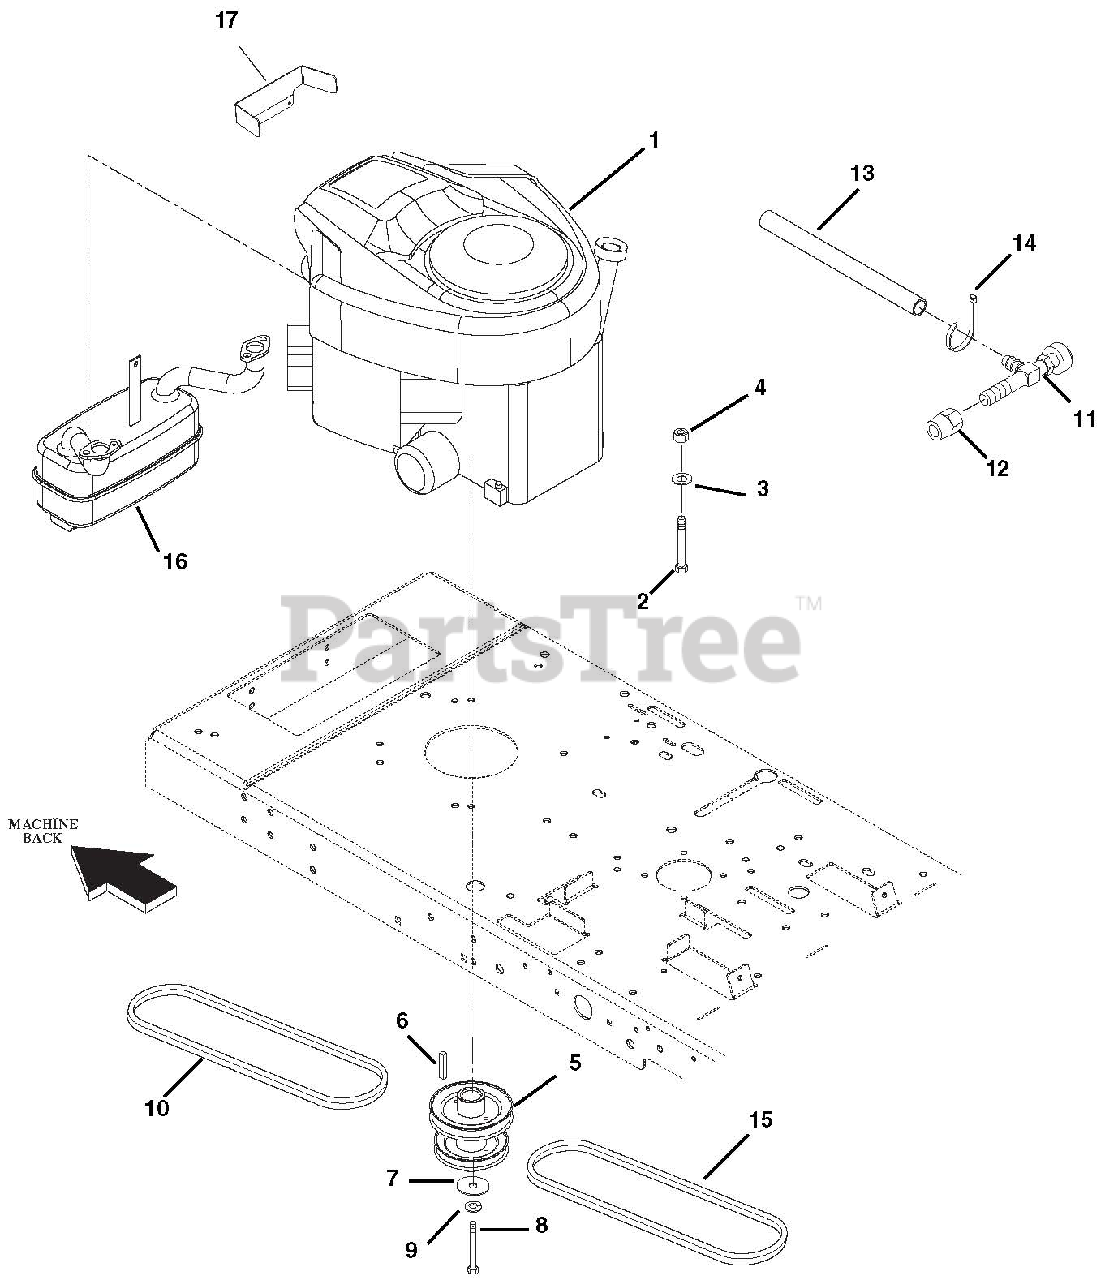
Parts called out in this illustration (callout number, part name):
1	ENGINE, B&S INTEK 20HP V TWIN
2	@BLT-HEX .31-18X1.50 GR5 YWZC
3	WSHR-FL-STL .328X1.0X.094 YWZC
4	@NUT-LK-NYL .312-18 YWZC
5	ENGINE SHEAVE 4.50
6	KEY-SQ .25 X 2.50 X .25 SAE
7	WSHR-FL-STL .469X2.00X.25 YWZC
8	BLT-HEX .44-20X3.00 GR5 YWZC
9	@WSHR-LK .44X.109 REG YWZC
10	V-BELT, 4L-RAW EDGE
11	COCK, OIL DRAIN
12	ADAPTER, OIL DRAIN
13	TUBE OIL DRAIN
14	CABLE TIE LG 5-1/2
15	V-BELT, HB-WRAPPED
16	MUFFLER ASSEMBLY
17	MUFFLER SHIELD
